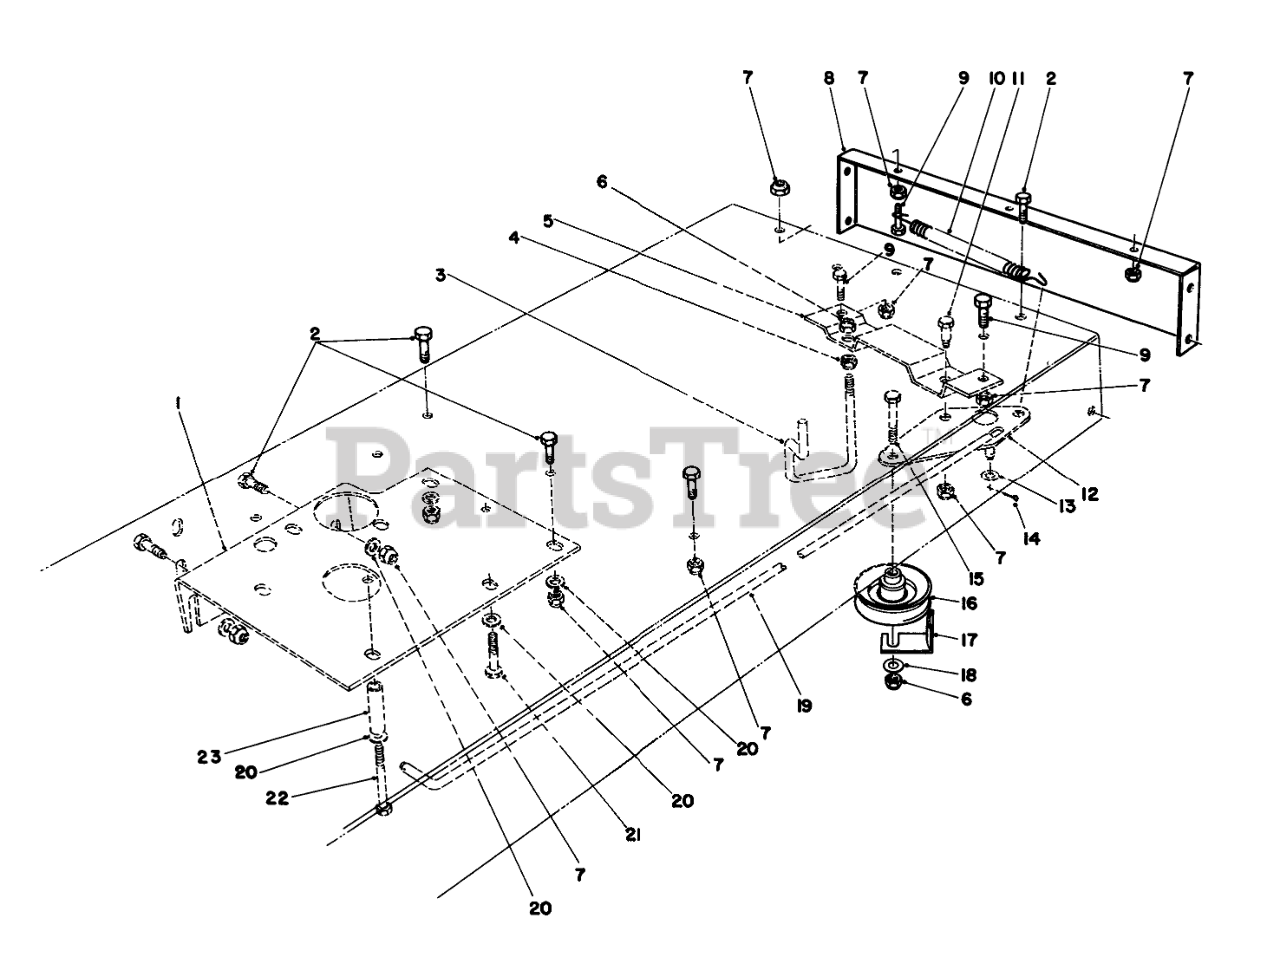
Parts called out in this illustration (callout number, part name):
1	REINF PLATE R
2	SCREW-HH
3	BELT GUIDE
4	NUT-LOCK, SIDE
5	TRACT SUPP BRKT B
6	NUT-LOCK, CONE
7	NUT-LOCK, NI
8	REAR FRAME R
9	SCREW-HH
10	TRACTION SPRING
11	BOLT-SHOULDER
12	TRACTION PIVOT BRKT
13	WASHER-FLAT
14	PIN-COTTER
15	SCREW-HH
16	PULLEY-IDLER
17	RETAINER-BELT
18	WASHER-FLAT
19	TRACTION ROD
20	WASHER-PLAIN
21	Screw-HH
22	SCREW-HH
23	OUTER TUBE SPACER
